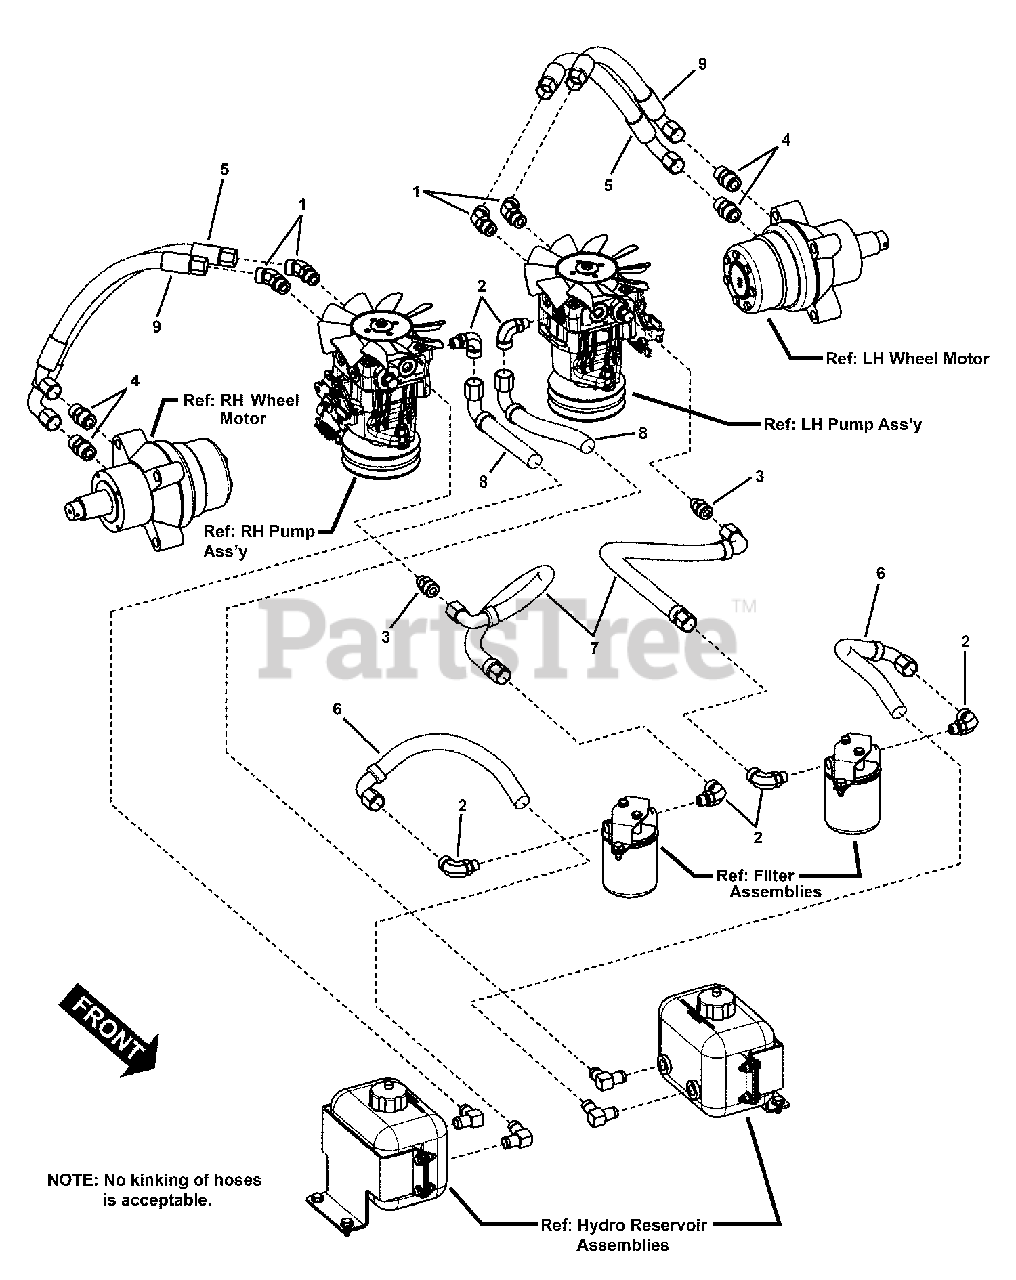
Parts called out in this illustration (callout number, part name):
1	CONNECTOR, 45-Degree Hydraulic (Parker # V5OLO-S)
2	CONNECTOR, 90-Degree Hydraulic (Parker # 8-6 C5OLO-S)
3	CONNECTOR, Straight Hydraulic (Parker # 8-6 F5OLO-S)
4	CONNECTOR, Straight Hydraulic (Parker # 8-10 F5OLO-S)
5	HOSE, 17-1/2" Hydraulic (Parker # F436BKJCJ5080808-17.5)
6	HOSE, 18-1/2" (Parker R836BKJCJ9090808-18.5)
7	HOSE, 12-1/4" (Parker # R836BKJ9NR080008-12.5)
8	HOSE, 6-1/2" (Parker # R836BKJ9NR080008-6.5)
9	HOSE, 15-1/2" Hydraulic (Parker # F436JCJ9080808-15.50)
